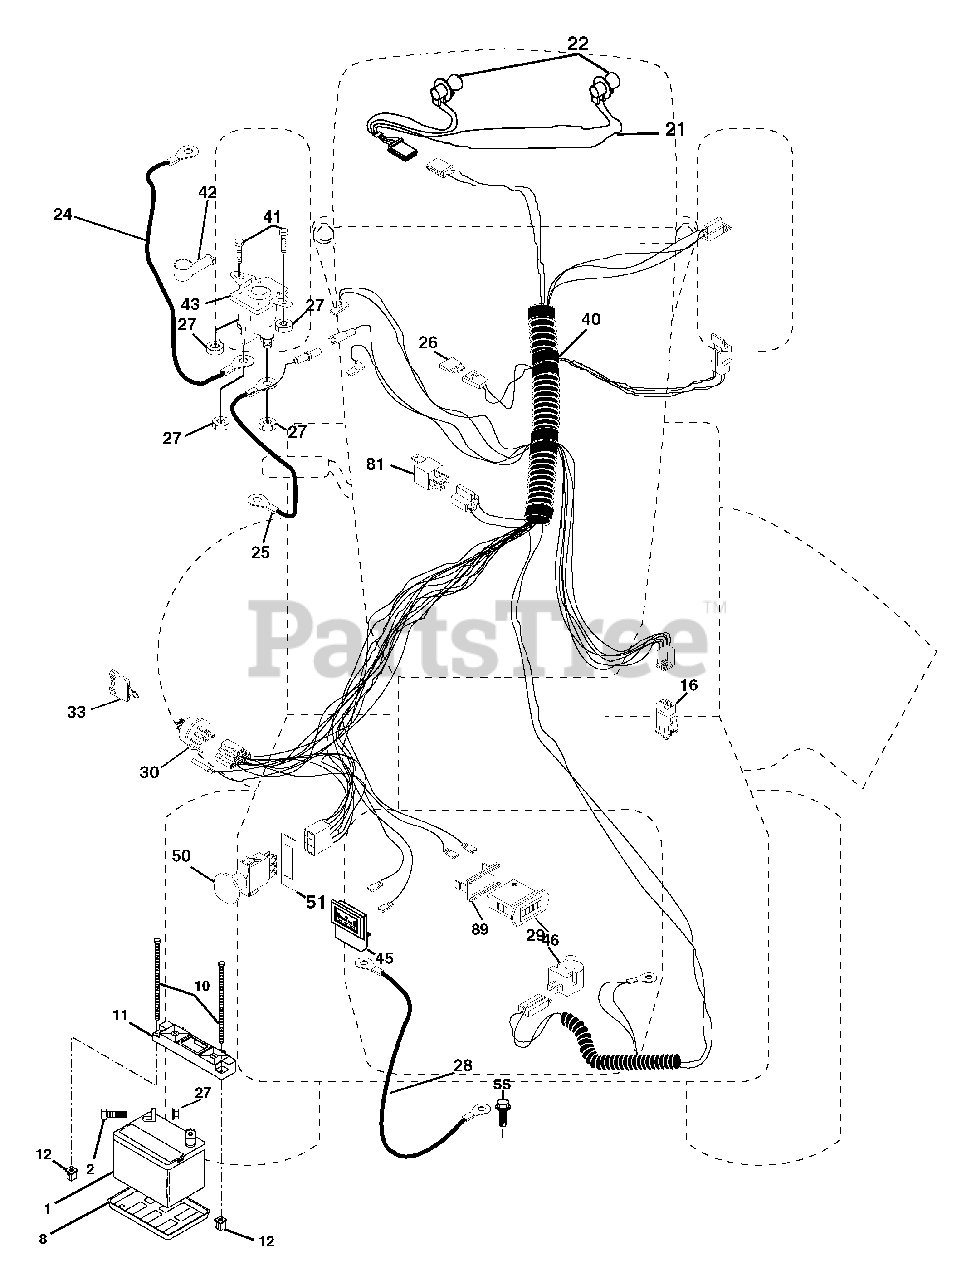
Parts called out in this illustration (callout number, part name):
1	Battery 12 Volt 35 AMP
2	Bolt Hex Hd 1/4-20unc X 3/4
8	Tray Battery
10	Bolt Brt Frt 1/4-20 x 75 Ainc
11	Holddown Battery Front Mount
12	Nut Push Nylon 1/4 Battery Frt
16	Switch Interlock
21	Harness Asm Light W/4152j
22	Bulb Light #1156
24	Cable Battery 6 Ga 11 red
25	Cable Battery 6 Ga 22 red w/16 wire
27	Nut Keps Hex 1/4-20 Unc
28	Cable Ground 6 Ga 21 black
29	Switch Plunger Nc Gray
30	Switch Ign
33	Key Ign Molded Generic
40	Harness Ign.
41	Bolt Blk Fin Hex 1/4 - 20 x 1/2
42	Cover Terminal Red
43	Solenoid
45	Ammeter Rectangular 15 Amp
46	Meter Hour
50	Switch PTO
51	Ring Retainer
55	Screw Thdrol 5/16-18 x 1-1/2 Tyt
81	Relay Asm.
89	Bracket Snap-In Hourmeter
